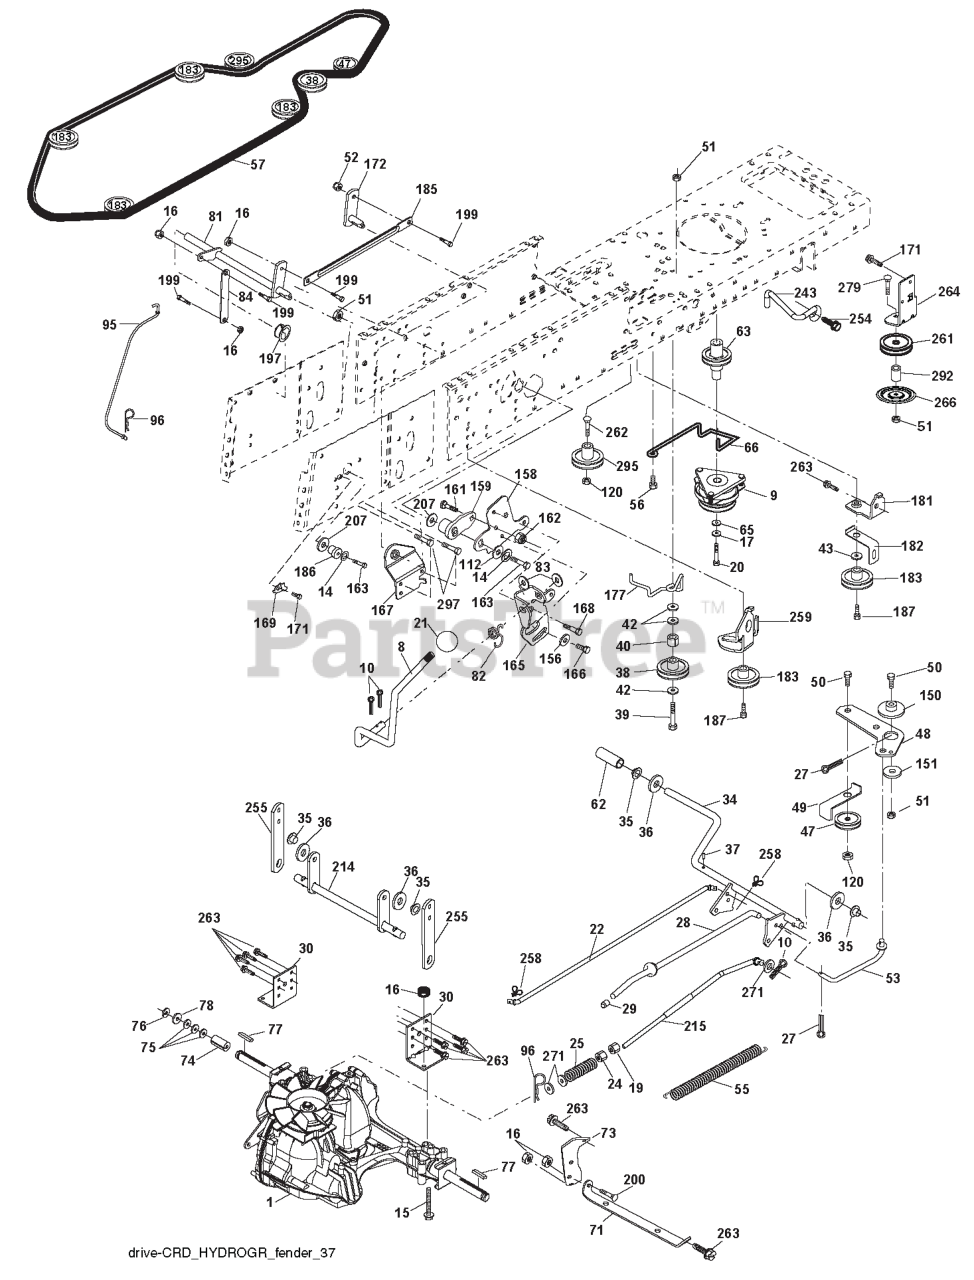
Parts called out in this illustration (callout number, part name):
8	ROD SHIFT FENDER ADJUST LT
9	CLUTCH.ELECTRIC.OGURA.EURO.
10	PIN COTTER
14	LOCKWASHER
15	BOLT HEX 5/16-18 GR 5
16	NUT.71038.31-18.HEX.NYLOCK
19	NUT
20	BOLT HEX 7/16-20X4-1/4"
21	KNOB.DUCKHEAD.1/2
22	ROD
24	NUT
25	SPRING BRAKE ROD
27	COTTER PIN
28	ROD, PARKING BRAKE
29	PLUNGER CAP
30	BRKT, TRNSXLE MNT 20"
34	SHAFT, FOOT PEDAL
35	BEARING.NYLON
36	WASHER LT
37	DRIVE PIN
38	PULLEY.FLAT
42	WASHER
43	WASHER T
47	IDLER PULLEY
48	BELLCRANK, CLUTCH
49	RETAIN BELT
50	BOLT.3/8-16X1.50
52	LOCKNUT
53	LINK.CLUTCH.7.66.2005
55	SPRING, RETURN LT
56	SCREW.3/8-16
57	V-BELT 113"
62	PEDAL COVER T
63	PULLEY.ENGINE.CVX.LT
65	LOCKWASHER
66	KEEPER BELT ENGINE
71	STRAP TORQUE LH HYDRO
73	STRAP TORQUE RH HYDRO
74	SPACER AXLE
77	SQUARE KEY
81	ASM.CROSS.SHAFT.REAR.CRD.0510
82	SHIFT SPRING
83	WASHER
84	LINK.PNT.TRANSAXLE.0510.CRD
95	LINK
96	RETAINER M
112	WASHER LT
120	NUT LOCK FLG 3/8-16 UNC
150	BUSHING.BELLCRANK.GRD.DR
151	WASHER 12/32X2X10GA
156	WASHER.SRRTD.5/16
158	BRACKET.SHIFT.MOUNT
161	BOLT
162	NUT.CROWNLOCK.1/4
163	BOLT
165	BRACKET.PIVOT.LEVER
166	CAPSCREW.HXHD.FLG.5/16-18X.625
167	BRACKET.SUPT.SHIFT.CRD
168	BOLT.SHOULDER.5/16-18X
169	PLATE.FASTENING.CROSS.SHAFT
171	SCREW LT
172	LINK
181	BRACKET
182	BELT GUIDE
183	PULLEY.V-IDLER.
185	LINK
186	HUB.TAPERED.ROUND.CRD
187	BOLT.5/16-18X1.25
197	NYLINER SNAP 5/8" ID
199	BOLT SHOULDER 5/16-18 UNC
200	BOLT
207	WASHER NYL
214	LEVER
215	ROD
243	BRACKET, ANTI-ROTATION
254	SCREW 3/8-16X1
255	SHAFT
258	CLIP RETAINER
259	BRACKET
261	FLAT IDLER PULLEY
263	SCREW, 3/8-16X3/4
264	BRACKET.IDLER
266	PROTECTOR
271	WASHER
279	BOLT
292	SPACER
295	PULLEY IDLER COMPOSITE
297	SCREW LT.3/8-46X5/8
